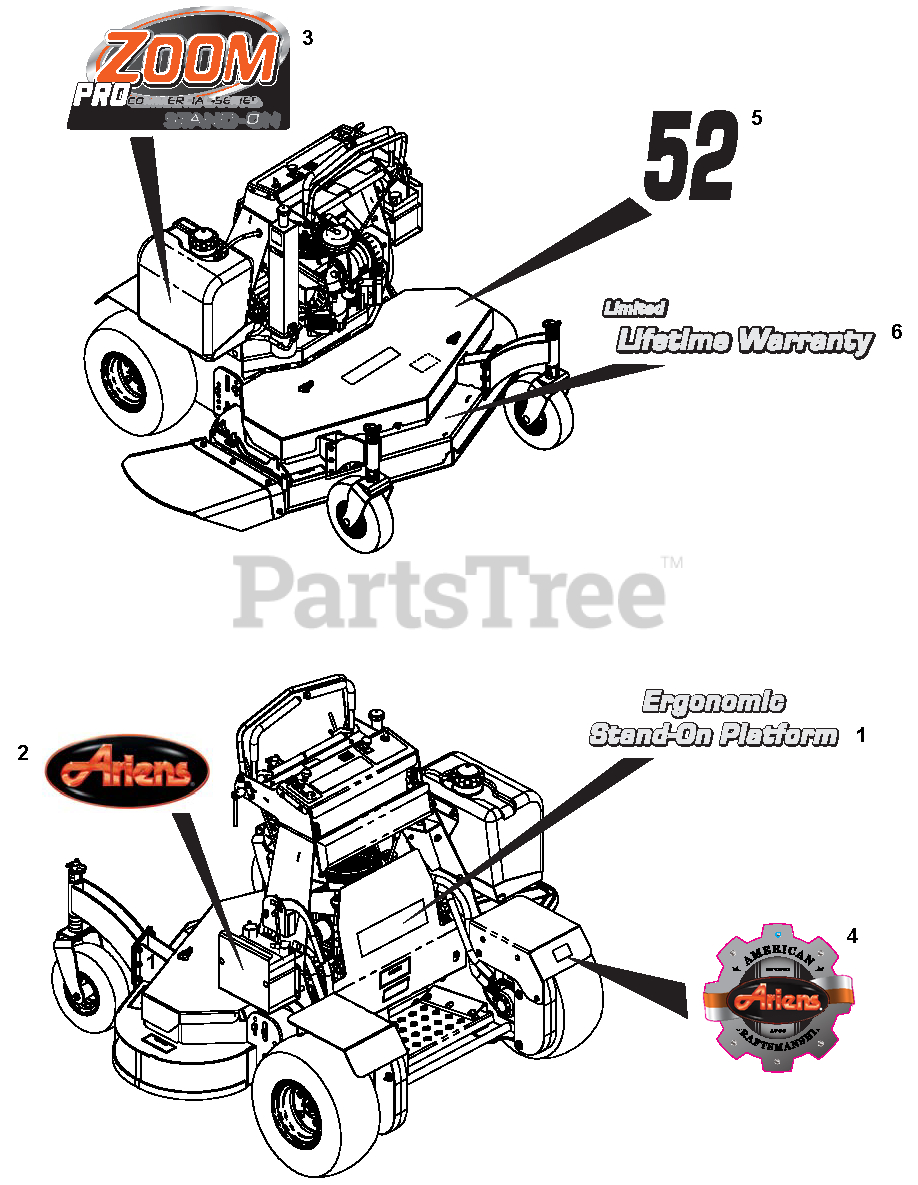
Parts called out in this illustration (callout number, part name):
1	DECAL, UNIT FEATURE 52 STANDON
2	DECAL, ARIENS JEWEL
3	DECAL, PRO ZOOM 4.82"
4	Decal, Ariens Heritage Large
5	DECAL, "52" (PROZOOM DECK)
6	DECAL, LIMITED LIFETIME WARR
